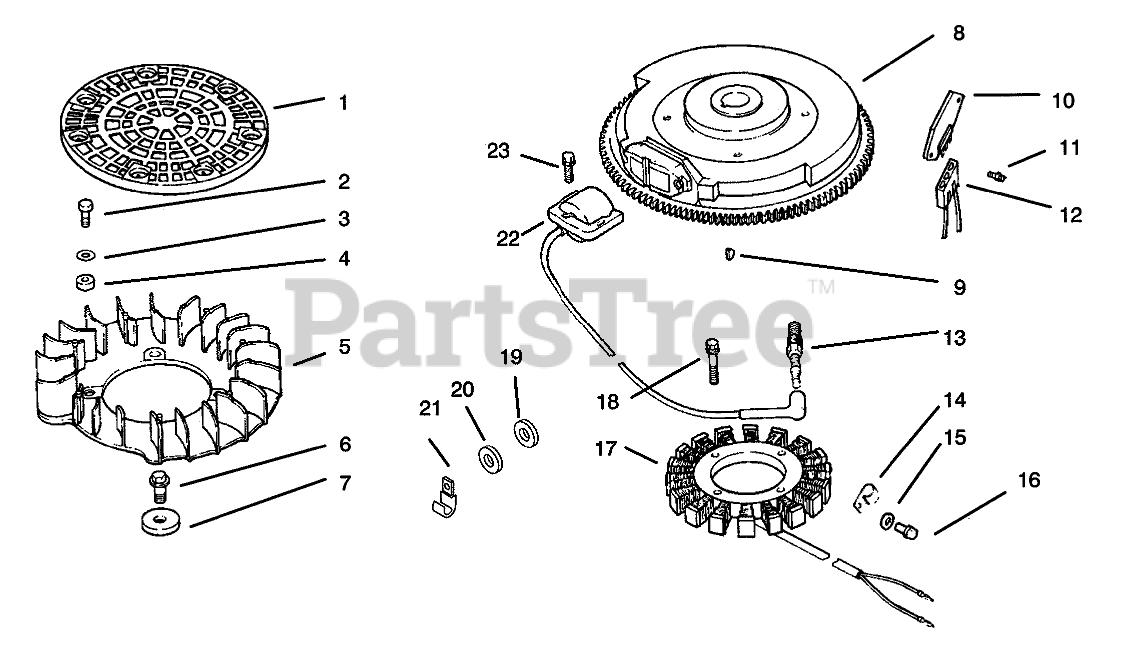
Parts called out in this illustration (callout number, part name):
1	Screen-Grass
2	Screw
3	Washer
4	Spacer-Fan
5	Fan
6	Screw
7	Spacer
8	Flywheel
9	Key
10	Rectifier-Regulator
11	Screw
12	Connector
13	Plug-Spark
14	Clip
15	Washer
16	Screw
17	Stator-15 Amp
18	Screw
19	Washer
20	Washer
21	Clip
22	Module-Ignition
23	Screw
